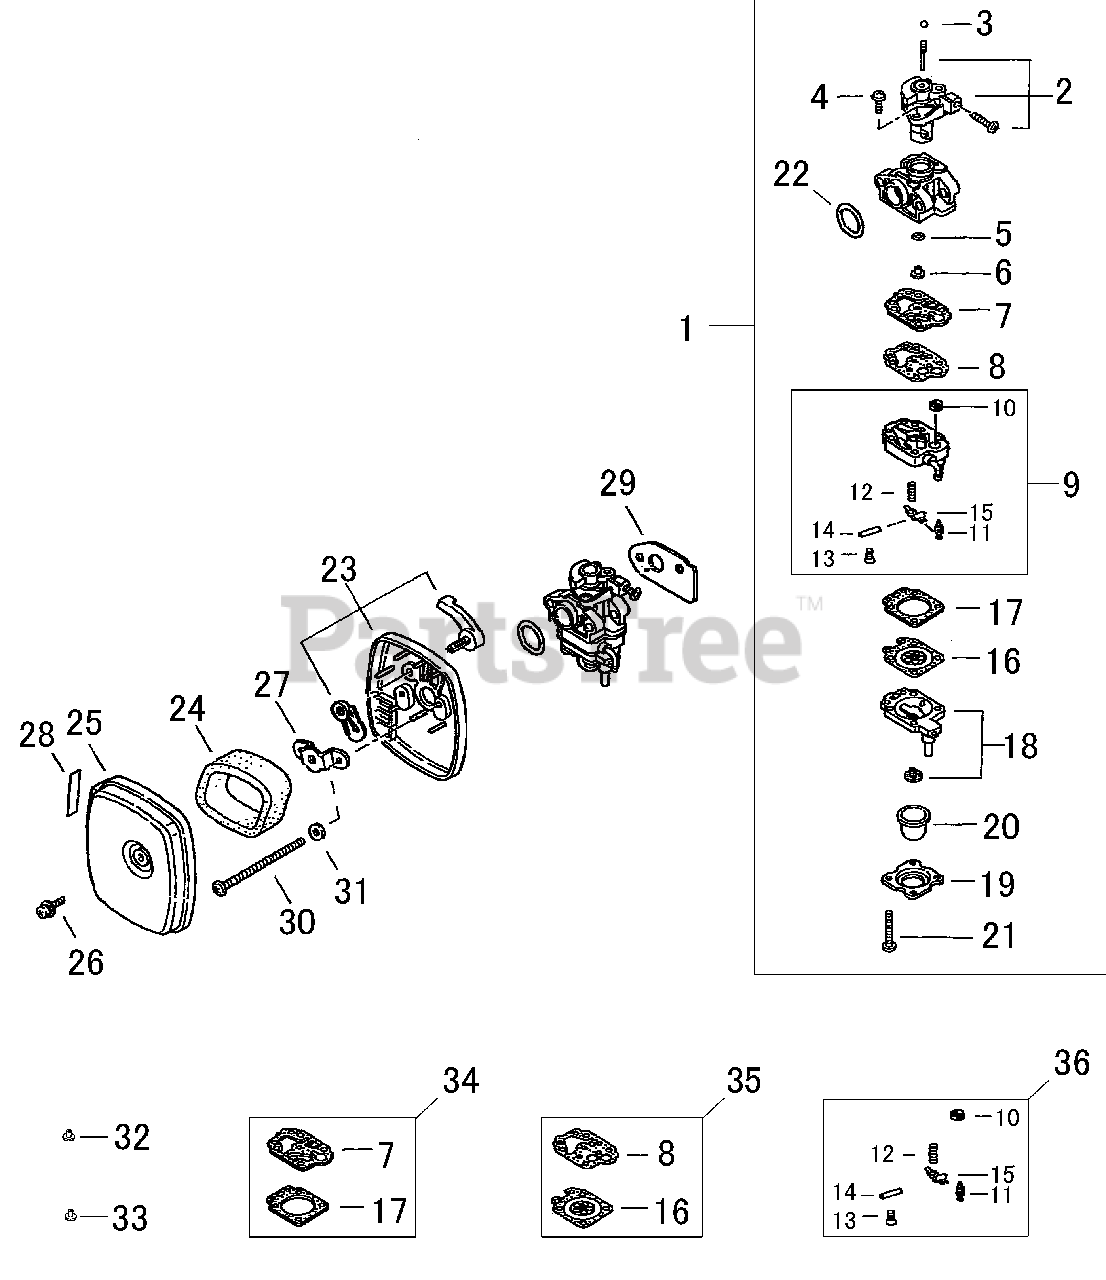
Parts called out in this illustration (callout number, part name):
2	VALVE ASSY, THROTTLE
3	PLUG
4	SCREW, THROTTLE COLLAR
5	O-RING
6	JET, MAIN #38
7	GASKET, PUMP
7-1	CARBURETOR
8	DIAPHRAGM, PUMP
9	BODY ASSY, PUMP
10	SCREEN, FUEL INLET
11	VALVE, INLET NEEDLE
12	SPRING, METERING LEVER
13	SCREW
14	PIN, METERING LEVER
15	LEVER, METERING
16	DIAPHRAGM, METERING
17	GASKET, METERING DIAPHRAGM
18	BODY ASSY, PURGE
19	RETAINER, PURGE BULB
20	BULB, PURGE
21	SCREW
22	O-RING 15
23	BASE ASSY, AIR FILTER
24	FILTER
25	COVER, AIR FILTER
26	SCREW
27	BRACKET
28	LABEL, CHOKE
29	GASKET, INTAKE
30	SCREW
31	WASHER, FLAT 5.5×10×0.8
32	JET, MAIN
33	JET, MAIN #34
34	GASKET KIT
35	DIAPHRAGM KIT
36	VALVE KIT, INLET NEEDLE
